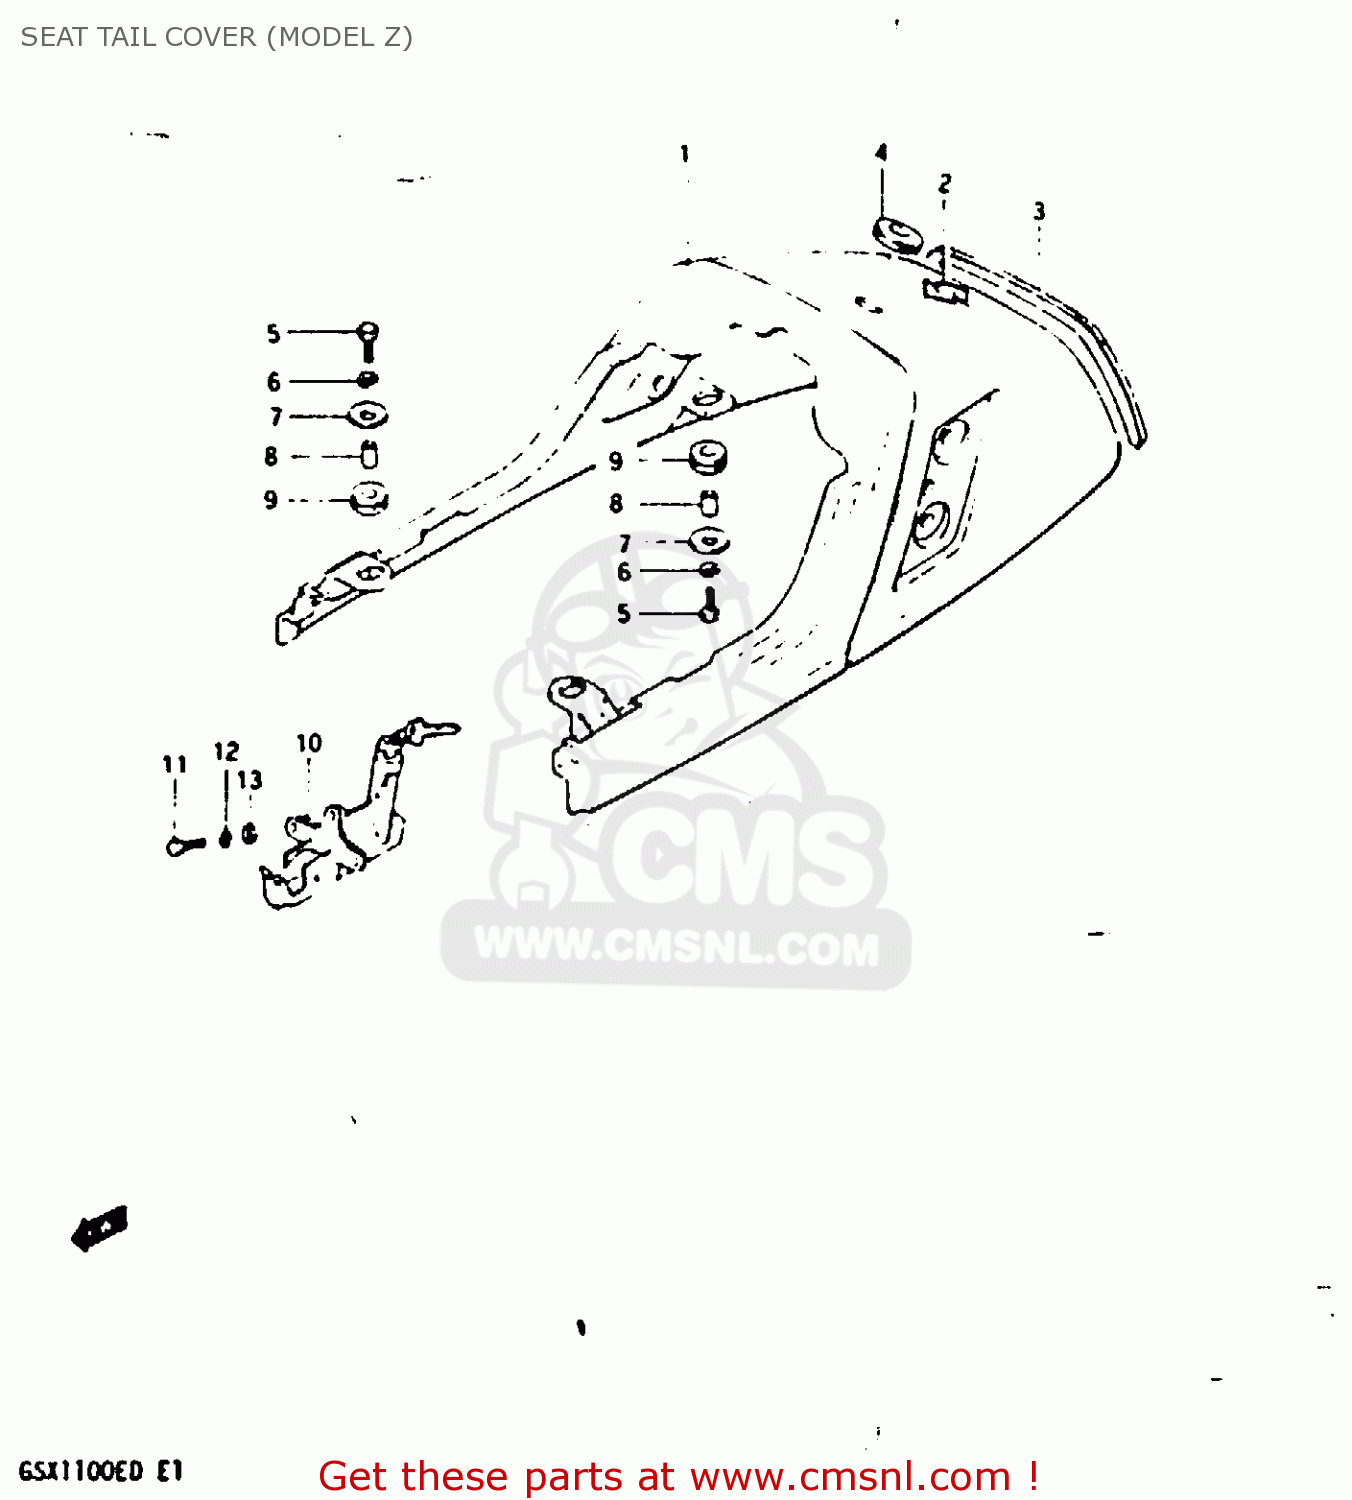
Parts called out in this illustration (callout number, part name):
1	COVER,SEAT TAIL
2	EMBLEM (S)
3	RUBBER,BLIND,SEAT TAIL COVER
4	GROMMET,SEAT LOCK HOLE
5	BOLT
6	LOCK WASHER
7	WASHER(6,5X22X1.6)
8	SPACER(6.5X10.5X12)
9	CUSHION
10	LOCK SET,SEAT
11	BOLT
12	LOCK WASHER
13	WASHER
